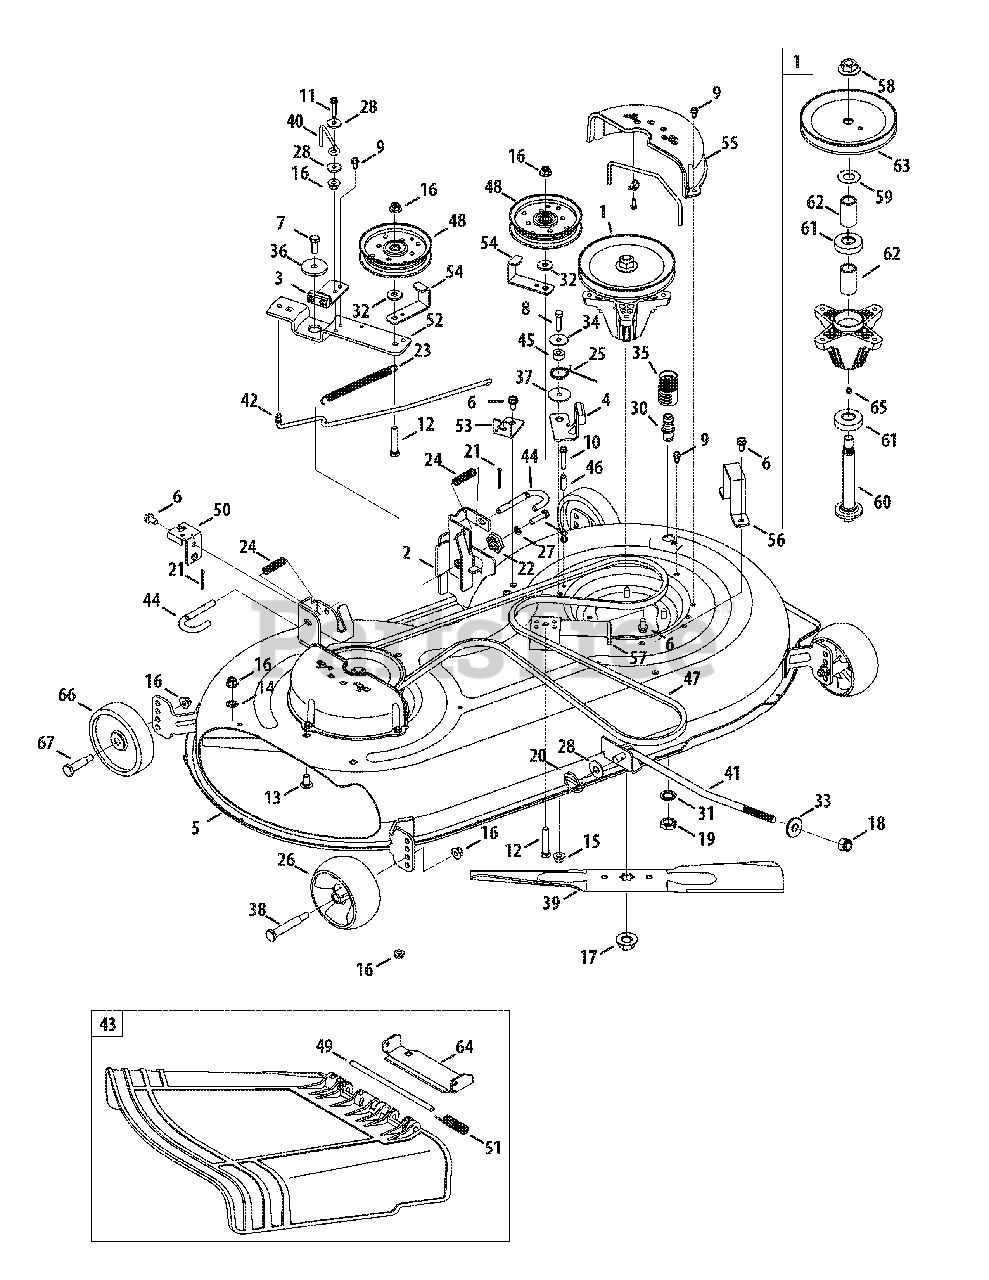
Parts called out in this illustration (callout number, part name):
1	Spindle Ass’y, Pulley, 6.3 Dia
2	Bracket Ass’y, Deck, Hanger LH
3	Brake Ass’y, Deck
4	Brake Ass’y, Deck
5	Deck Shell, Offset, 42"
6	Screw, Self-tapping, 5/16-18, .750
7	Hex Screw, 3/8-16, 1.00, Gr5, Std
8	Hex Screw, 5/16-18, 1.25, Gr5, Std
9	Screw, Self-tapping, 1/4-20, 0.500
10	Screw, Self-tapping, 1/4-20, 1.500
11	Screw, Self-tapping, 1/4-20, 1.250
12	Hex Screw, 3/8-16, 2.00, Gr5, Std
13	Bolt, Carriage, 3/8-16, 0.75, Gr1
14	Nut, Push, 3/8
15	Nut, Flange Lock, 5/16-18, Grf
16	Nut, Flange Lock, 3/8-16, Grf
17	Nut, Flange, 5/8-18
18	Nut, Lock, 1/2-13
19	Nut, Hex, M16-1.5
20	Pin, Lynch, .1875
21	Pin, Cotter, 1/8 x 1.25
22	Gear, Deck, Adjustment
23	Spring, Extension, .62 Dia x 6.12
24	Spring, Comp, .535 OD x 1.751
25	Spring, Torsion, .992 I.D x 1.17 O.D
26	Wheel, Deck, 5.0 Dia Ball
27	Washer, Lock, 5/16, Regular Duty
28	Washer, Flat, .265 x .938 x .120
29	Washer, Flat, .531 x 1.25 x .100
30	Port, Water
31	Washer, Lock, 5/8, Int Tooth
32	Washer, Flat, .385 x .870 x .092
33	Washer, Bell, .63 x 1.25 x .18
34	Washer, Flat, .330 x 1.25 x .06
35	Adapter, Water Port
36	Spacer, Shoulder, .8840 x .190
37	Spacer, Shoulder, .5000 x .1475
38	Bolt, Shoulder, .496 x 2.50, 3/8-16
39	Blade, Cut, 21.23" 2-In-1, Cub
40	Rod, Keepr, Belt
41	Rod, Lift, Deck, Frt, 13.7
42	Rod, Control, Brake
43	Chute Ass’y, Deflector
44	Rod, Handle, Deck Rel .375 Dia
45	Spacer, .315 x .750 x .375
46	Spacer, .260 x .375 x 1.030
47	Belt, V Type, A Sec x 96.5
48	Pulley, Idler, 4.25"Dia
49	Pin, Hinge, Dia .3125 x 7.96
50	Bracket, Cable, Deck Engage
51	Spring, Torsion, .44 I.D. x 2.0
52	Bracket, Idler, Pivot
53	Bracket, Cable, Deck Engage
54	Bracket, Guard, Belt, 4.25 Pulley
55	Cover, Belt
55	Rod Keeper, Belt
55	Clamp, Casing
55	Screw-B, #10-16, .625
57	Bracket, Support, Stationary Idler
58	Nut, Flange, 5/8-18
59	Washer, Flat, .760 Idx1.50 OD
60	Shift, Spindle, 6.11
61	Bearing, Ball, .787id x 1.85 Odx.551
62	Spacer, .792 x 1.060 x 1.860
63	Pulley, Deck, 6.3 Dia
64	Bracket, Chute
65	Lube Fitting, 3/16
66	Wheel, Deck
67	Bolt, Shoulder, .496 x 1.525, 3/8-16
